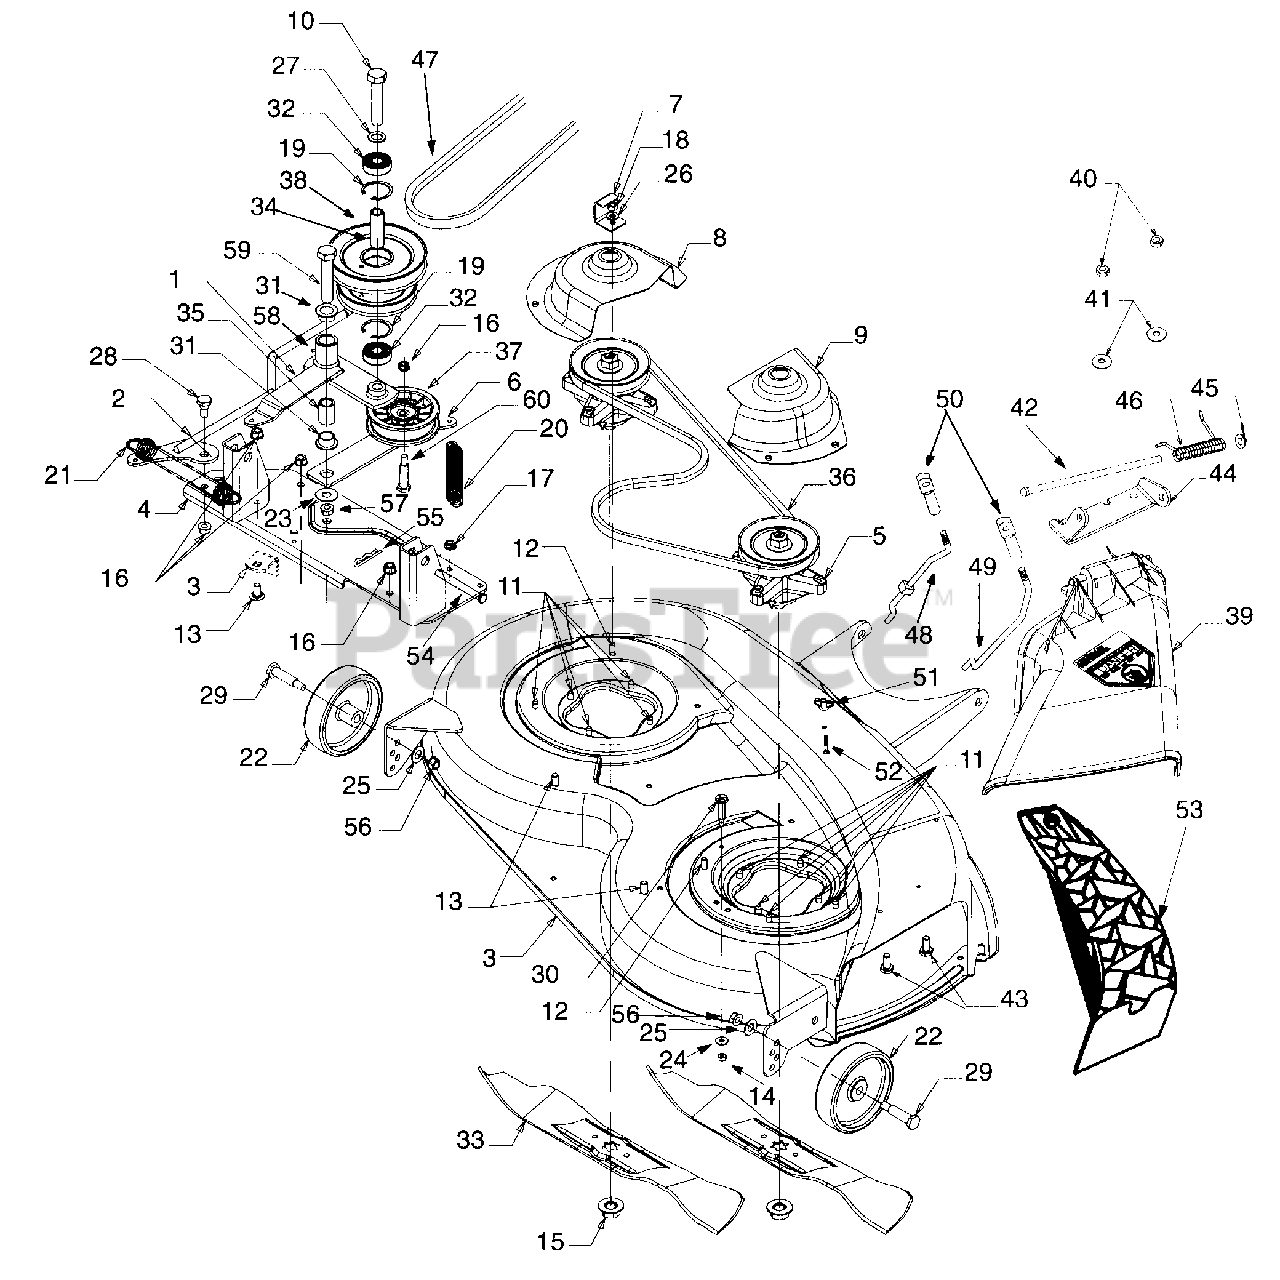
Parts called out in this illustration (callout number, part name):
10	Hex Hd. Cap Scr. 5/8-18:3.00 Lg.
11	Hx Ind Wsh Scr. TT 5/16-18:.750 Lg.
12	Hex Hd. Cap Scr. 5/16-18:.750 Lg.
13	Carr. Bolt 3/8-16 x .75 Lg.
14	Hex Nut 1/4-20
15	Flanged Hex Nut 5/8-18
16	Flanged Lock Nut 3/8-16
17	Hex Flanged Lock Nut 5/16-18
18	Nut 5/16-18
19	Internal Snap Ring
20	Extension Spring
21	Extension Spring
22	Deck Wheel
23	Fl. Washer .531 I.D. x 1.25 O.D. x .036
24	Bell Washer .265 x .75 x .062
25	Bell Washer .041 x .87 x .063
26	Fl. Washer 5/16
27	Fl. Washer 5/8 I.D. x 1.0 x .063
28	Shoulder Scr. 3/8-16
29	Shoulder Scr.
30	Shoulder Scr. .374 Dia. x 1.160 Lg.
31	Flange Brg. 3/4 I.D. x .52 Lg.
32	Bearing .625 I.D. x .574 O.D. x .470
33	Blade 19.38 Lg. Star
34	Spacer .50 O.D. x .75 I.D. x 2.25
35	Spacer .88 O.D. x .635 I.D. x 1.25
36	V-Belt
37	Flat Idler Pulley 3.5 O.D.
38	Double Pulley
39	Chute Deflector - Complete
40	Nut 1/4-20
41	Bell Washer
42	Hinge Pin
43	Hex Hd. Cap Scr. 1/4-20:.625
44	Hinge Mounting Bracket
45	Cap Speed Nut - 1/4 Rod
46	Torsion Spring
47	V-Belt
48	Front Lift Rod (LH)
49	Front Lift Rod (RH)
51	Wing Nut 1/4-20 Thd.
52	Hex Bolt 1/4-20 x 1"
53	Mulching Plug
54	Clevis Pin
55	Cotter Pin
56	Jam Nut 3/8-16
57	Nut 1/2-20
58	Lube Fitting
59	Hex Head Cap Screw 1/2-20:3
60	Hex Head Cap Screw 3/8-16:1.5
